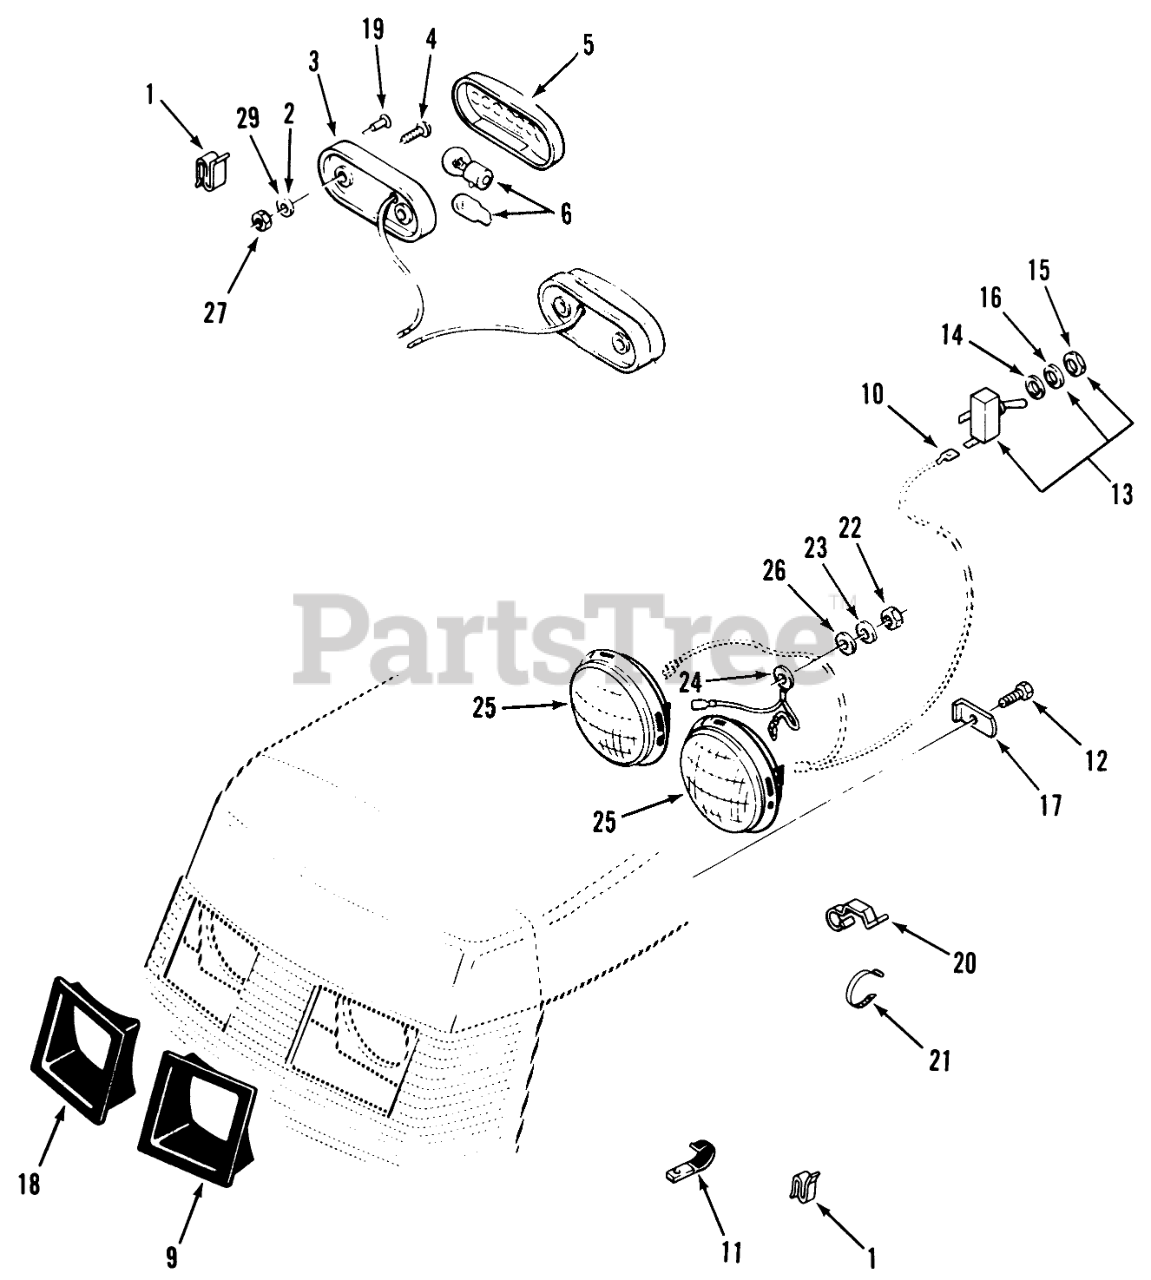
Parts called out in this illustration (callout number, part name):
1	SPEED CLIP
2	Lockwasher
3	BASE-TAIL LIGHT
4	Screw
5	LENS-TAIL LIGHT
6	Bulb
9	BEZEL-HEADLIGHT, LH
10	Terminal
11	CLIP
12	Bolt
13	SWITCH-LIGHTS
14	Washer
16	TAB-WASHER
17	LOCK-HEADLIGHT
18	BEZEL-HEADLIGHT, RH
19	RIVET-4
20	CLIP-WIRE
21	PLASTIC TIE
22	Nut
23	Washer-Lock
24	LIGHT GROUND WIRE
25	HEADLAMP
26	WASHER 5/16 SAE
27	Nut
29	WASHER
